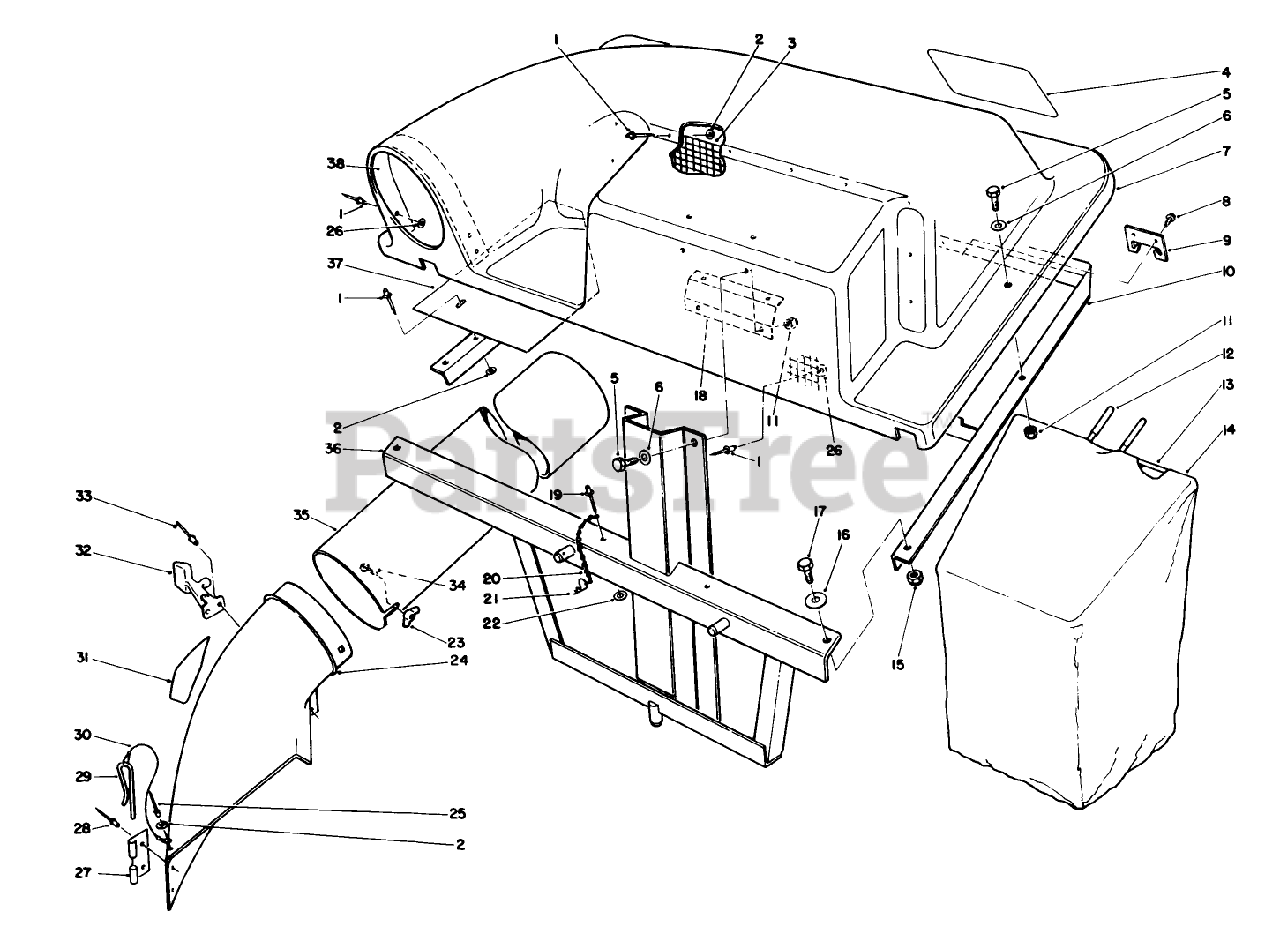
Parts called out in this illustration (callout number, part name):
1	Rivet-Pop
2	WASHER-PLAIN
3	SCREEN
4	DECAL-BAGGER, TWIN
5	SCREW-HH
6	WASHER-PLAIN
7	COVER-BAGGER, TWIN
8	Bolt 1/4-20
9	BRACKET-FRAME, BAG
11	NUT-LOCK, NI
12	GRIP-HANDLE, BAG
15	Locknut
16	WASHER-FLAT
17	SCREW-HH
21	PIN-HAIR
22	WASHER-BACK
23	NUT-WING SPECL
24	CHUTE ASM
25	RIVET-BLIND
26	WASHER-FLAT
27	BRACKET-MOUNTING, CHUTE
28	Rivet
29	PIN-LOCKING, CHUTE
30	LANYARD
33	RIVET-POP
34	BOLT-CARR
